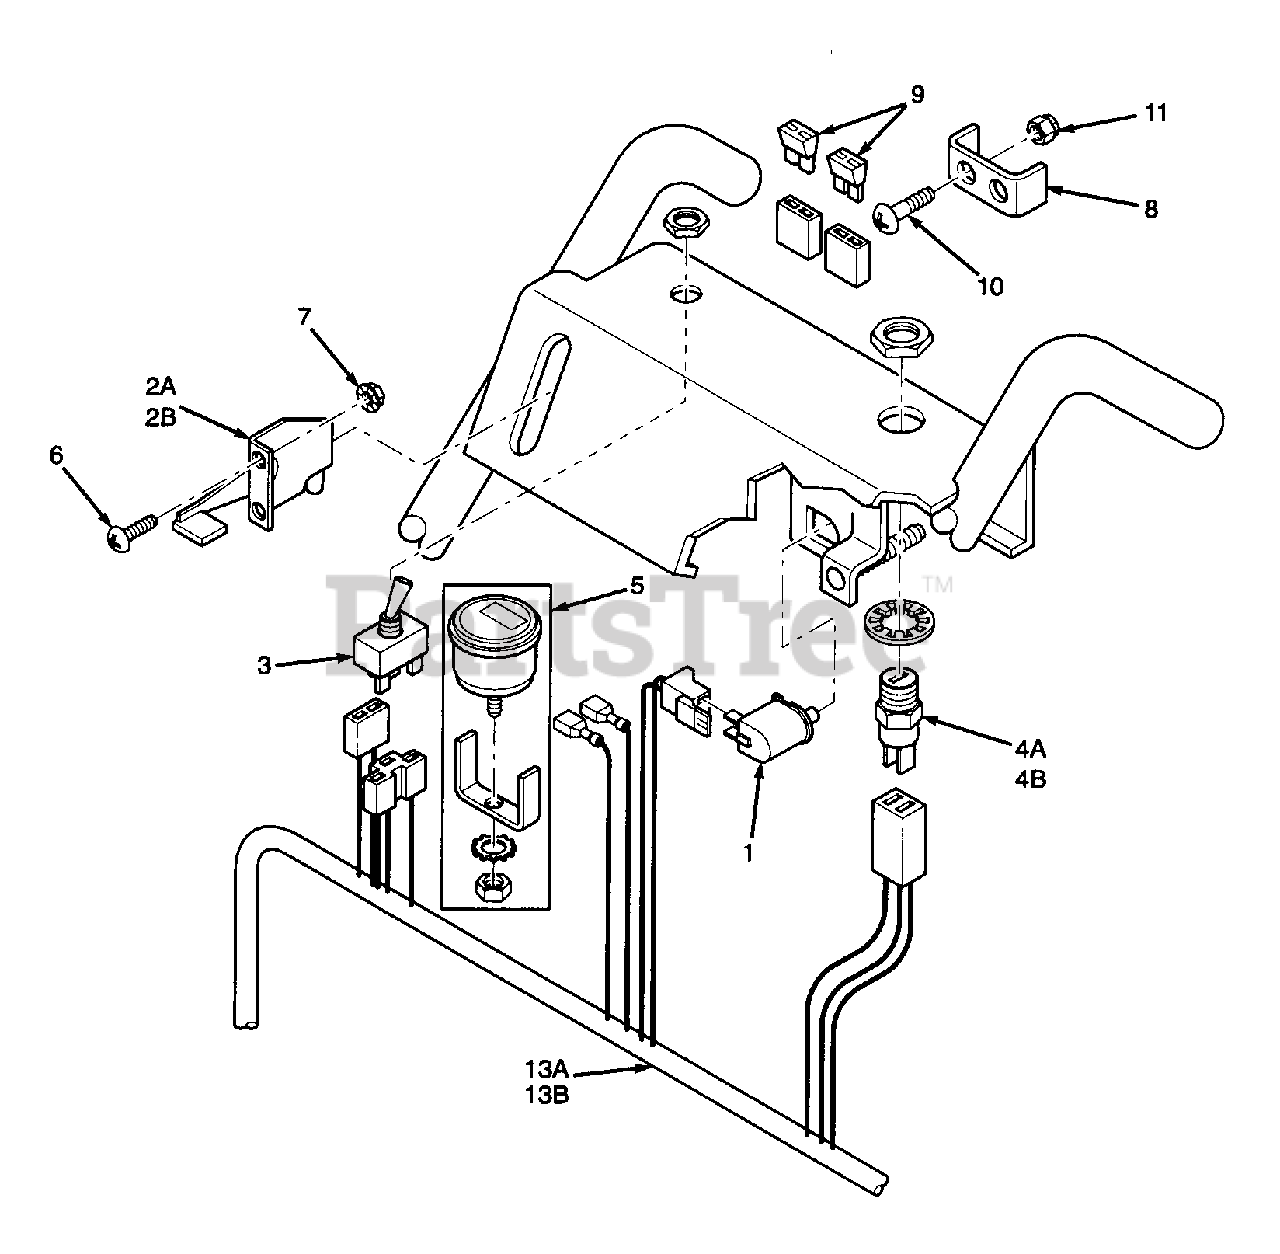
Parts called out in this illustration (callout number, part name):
1	Switch, Neutral Interlock
2A	Throttle Control
2B	Throttle Control
3	Engagement Switch, Electric Clutch
4A	Key Switch
4B	Key Switch
5	Hour Meter
6	Screw, #10-32 x .50 Phillips Washer Head
7	Nut, #10-32 Serrated Flange Hex Head
8	Bracket, Fuse Holder
9	Blade Fuse, 20A
11	Nut, #10-32 Elastic Stop
13A	Handle Wire Harness, Electric Start
13B	Handle Wire Harness, Manual Start
